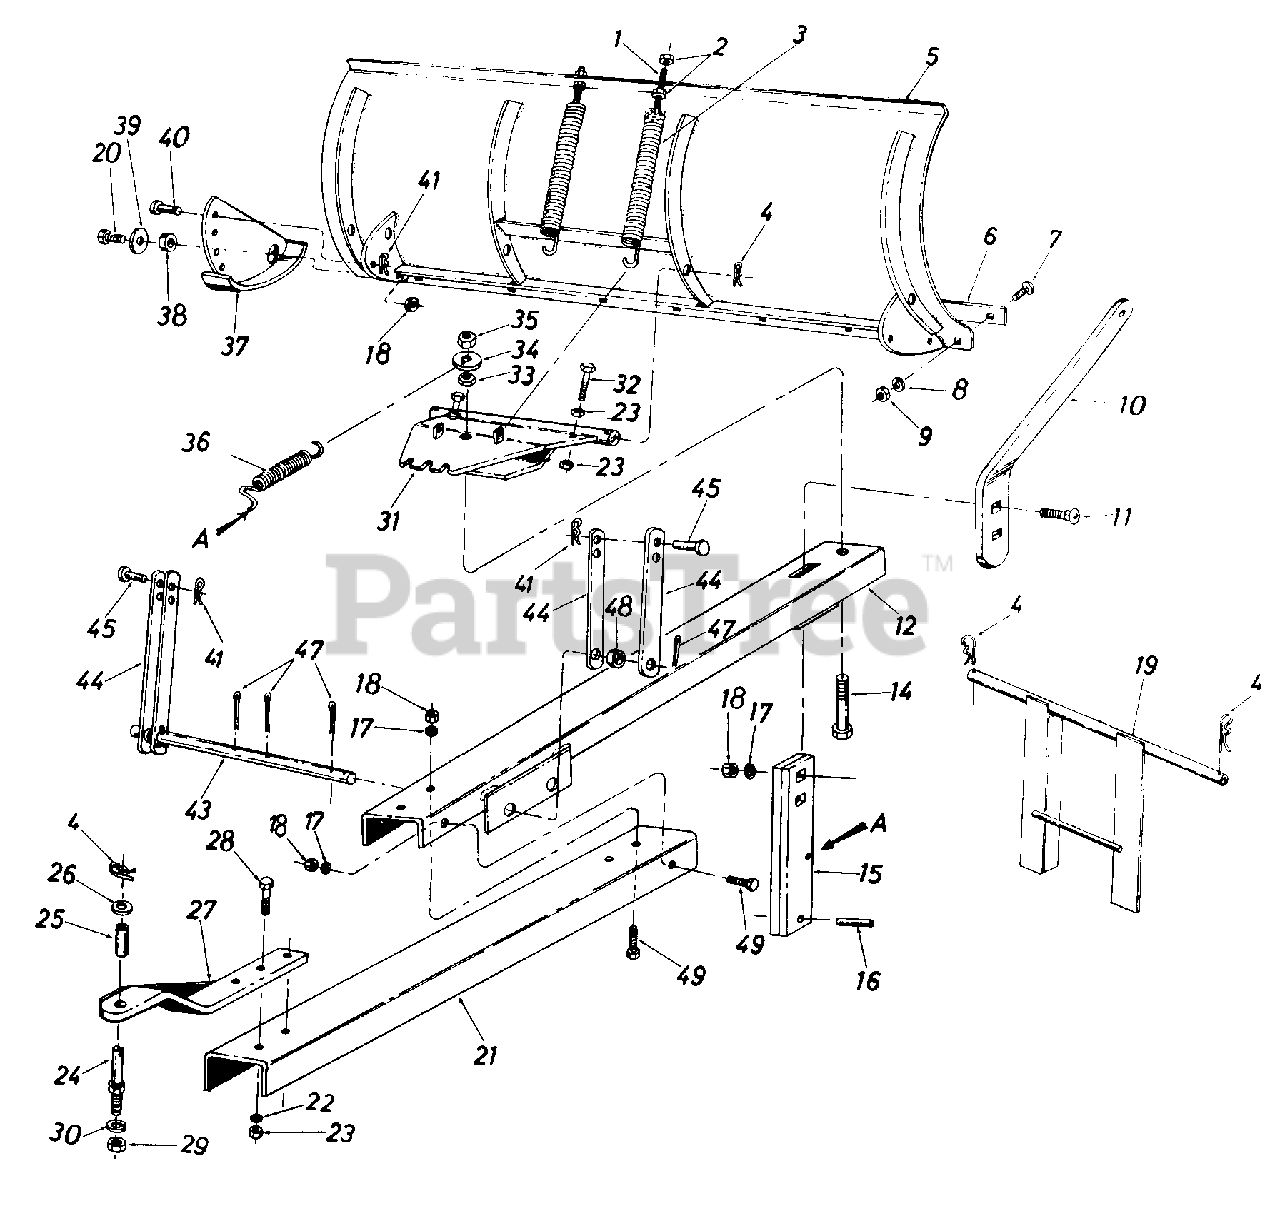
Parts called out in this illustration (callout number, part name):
1	Hex Bolt 3/8-16 x 4.5" Lg.
2	Hex Nut 3/8-16 Thd.
3	Blade Adjustment Spring
4	Int. Cotter Pin 5/32"
5	54" Blade Ass'y.
6	Wear Plate
7	Carriage Bolt 5/16-18 x .75" Lg.
8	L-Wash. 5/16" I.D.
9	Hex Nut 5/16-18 Thd.
10	Lock Extension Bar
11	Carriage Bolt 3/8-16 x 1.25" Lg.
12	Front Push Bar Ass'y.
14	Hex Bolt 3/4-10 x 3.5" Lg.
15	Angle - Lock Bar
16	Spring Pin Spiral .25" Dia. x 1"
17	L-Wash. 3/8" I.D.
18	Hex L-Nut 3/8-16 Thd.
19	Guide Bracket Ass'y.
20	Hex Bolt 3/8-16 x .75" Lg.
21	Rear Push Bar Channel
22	L-Wash. 1/2" I.D.
23	Hex Nut 1/2-13 Thd.
24	Link Clevis Pin
25	Spacer 21/32" I.D. x .75" Lg.
26	Fl-Wash. 21/32" I.D. x .09" O.D.
29	Hex Jam L-Nut 5/8-18 Thd.
30	L-Wash. 5/8" I.D.
31	Pivot Plate Ass'y.
32	Hex Bolt 1/2-13 x 2.0" Lg.
33	Hex Jam Nut 3/4-10 Thd.
34	Fl-Wash. 3/8" (Special)
35	Hex Lock Nut 3/4-10 Thd.
36	Angle Lock Spring
37	Skid Assembly
38	Bushing, Pivot Skid
39	Fl-Wash. .385" I.D. x 1.0" O.D.
40	Clevis Pin 5/16" Dia. x 3/4" Lg.
41	Int. Cotter Pin 3/32"
45	Clevis Pin 1/2" Dia. x 1.0" Lg.
47	Cotter Pin 1/8" Dia. x 1.25" Lg.
48	Spacer, Lift Link
49	Hex Bolt 3/8-16 x 1.0" Lg.
